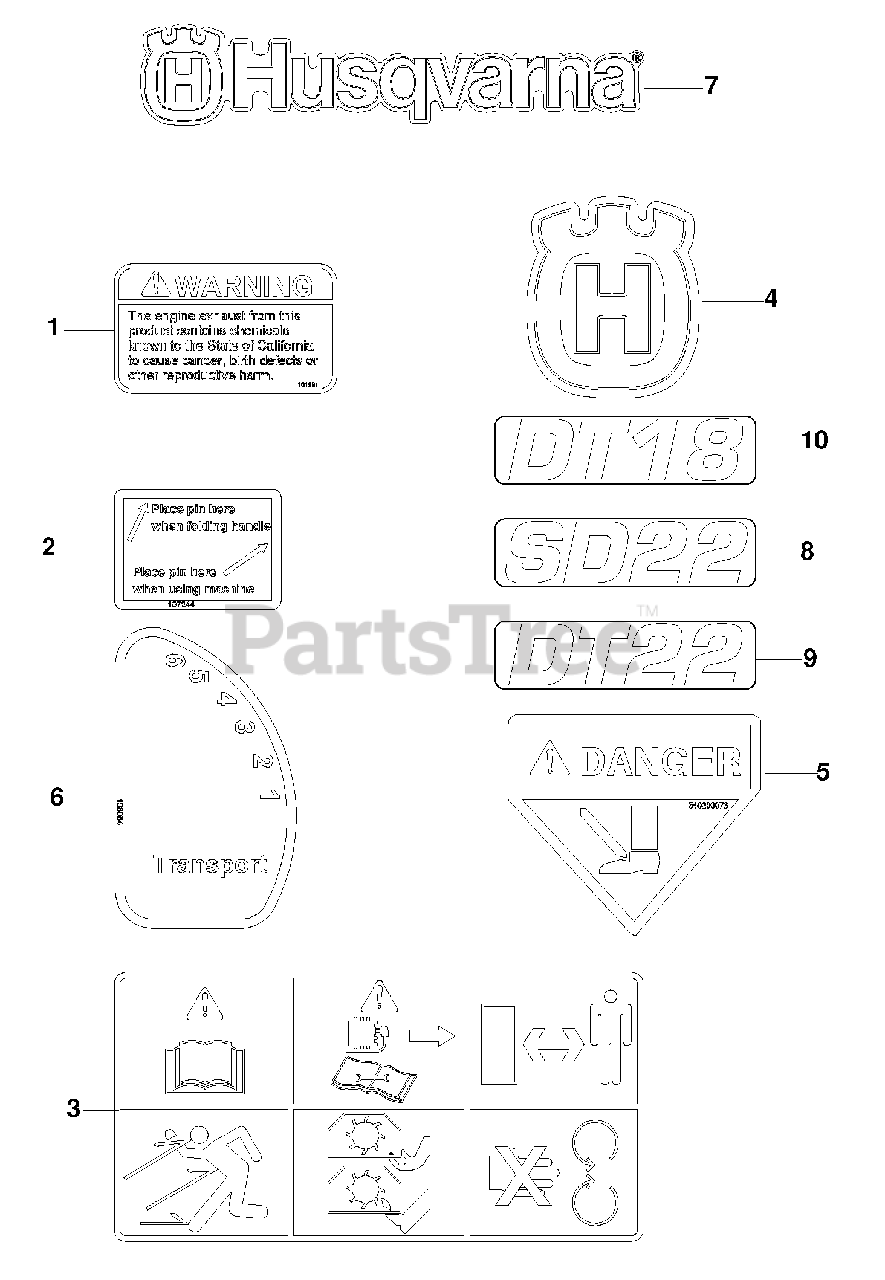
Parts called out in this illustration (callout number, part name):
1	DECAL, PROP 65
2	DECAL, HANDLE PIN
3	DECAL, SAFETY GRAPHICS
4	DECAL, CROWN
5	DECAL, DANGER FOOT
6	DECAL, DEPTH
7	DECAL, HUSQVARNA
8	DECAL, SD22
9	DECAL, DT22
10	DECAL, DT18
